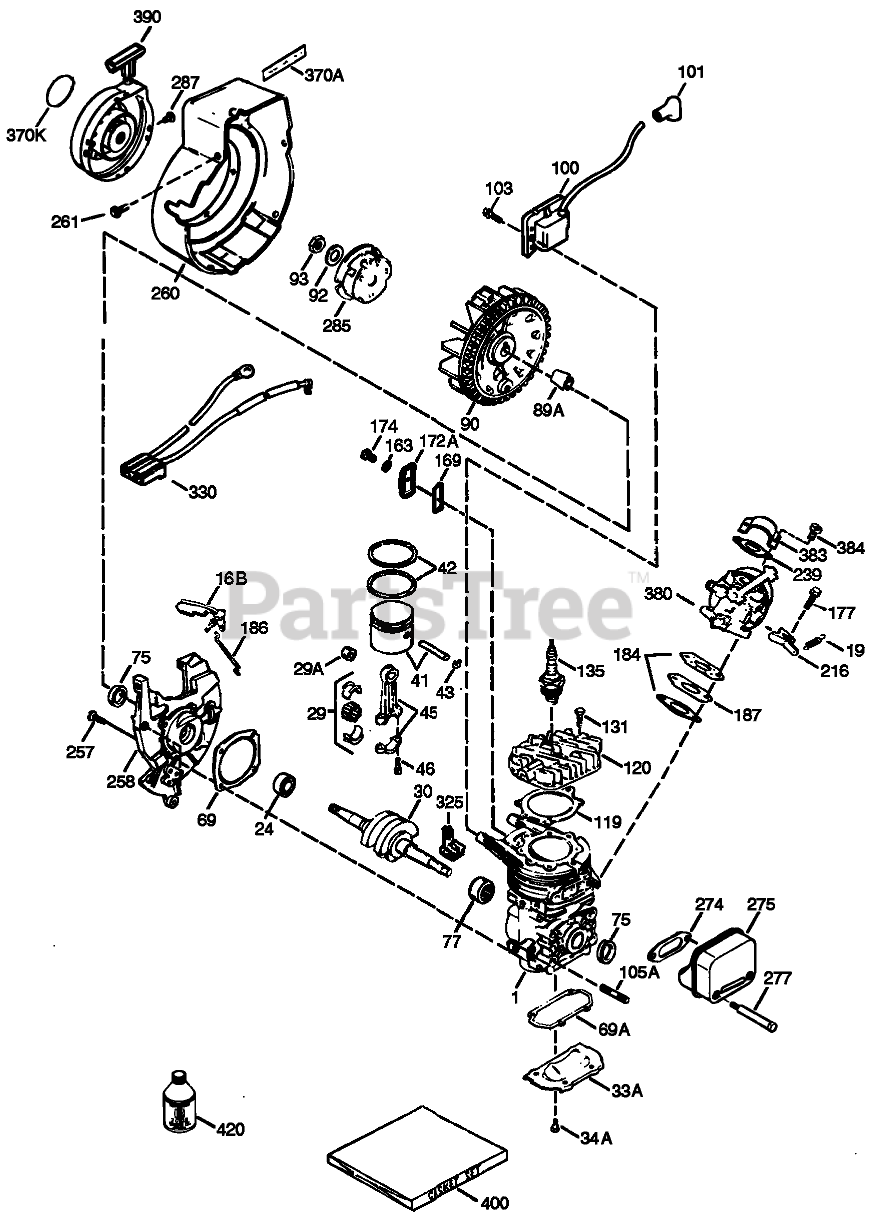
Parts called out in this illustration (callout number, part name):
1	Spec SV540-0019
16B	Vane-Air
19	Spring-Extention
24	Bearing-Ball
29	Needle Bearing and Liner Set (37 Needles)
29A	Bearing-Cartridge
30	Crankshaft
33A	Plate-Cover
34A	Screw (T-25, 10-24 x 1/2)
41	Piston & Pin ASM Piston & Pin Ass?y. (Incl. Ref. #43)
42	Ring Set
43	Ring-Retaning
45	Connecting Rod Ass?y. Piston & Pin ASM (Incl. Ref. #29, 29A, & 46)
46	Bolt-Rod, Connecting
69	Gasket-Cover, Cylinder
69A	Gasket-Plate, Cover
75	Seal-Oil
77	Bearing-Cartridge
89A	Blade (20 inch)
90	Flywheel
92	Washer-Belleville
93	Nut-Flywheel
100	Solid State Ignition (Incl. Ref. #101)
101	Cover-Spark Plug
103	Screw (T-15, 10-24 x 15/16)
105A	Stud
119	Gasket-Head, Cylinder
120	Head-Cylinder
131	Screw (T-30, 1/4-20 x 3/4)
135	Spark Plug-Resistor (R C J 8Y)
163	Washer
169	Cover-Compression, Release
172A	Cover-Release, Compression
174	Screw (T-25, 10-24 x 1/2)
177	Screw (5/32 Allen, 1/4-20 x 1)
184	Gasket-Carburetor
186	Governor-Link
187	Spacer
216	Lever-Adjusting, Rpm
239	Gasket-Cleaner, Air
257	Screw (T-30, 1/4-20 x 5/8)
258	Blower Housing Base (Incl. Ref. #75)
260	Housing-Blower
261	Screw (1/4-20 x 1/2)
274	Gasket-Exhaust
275	Muffler (Incl. Ref. #274 and 277)
277	Screw (1/4-20 x 2-3/4)
285	Cup-Starter
287	Screw (8-32 x 21/64)
325	Clip-Wire
330	Harness-Wire
370A	Decal-Lubrication
370K	Decal-Tecumseh Logo for Top of Recoil Starter
380	Carburetor
383	Baffle-Carburetor
384	Screw (T-25, 10-32 x 5/8)
390	Rewind Starter ASM
400	Gasket Set
420	2-Cycle Oil (8 oz.)
